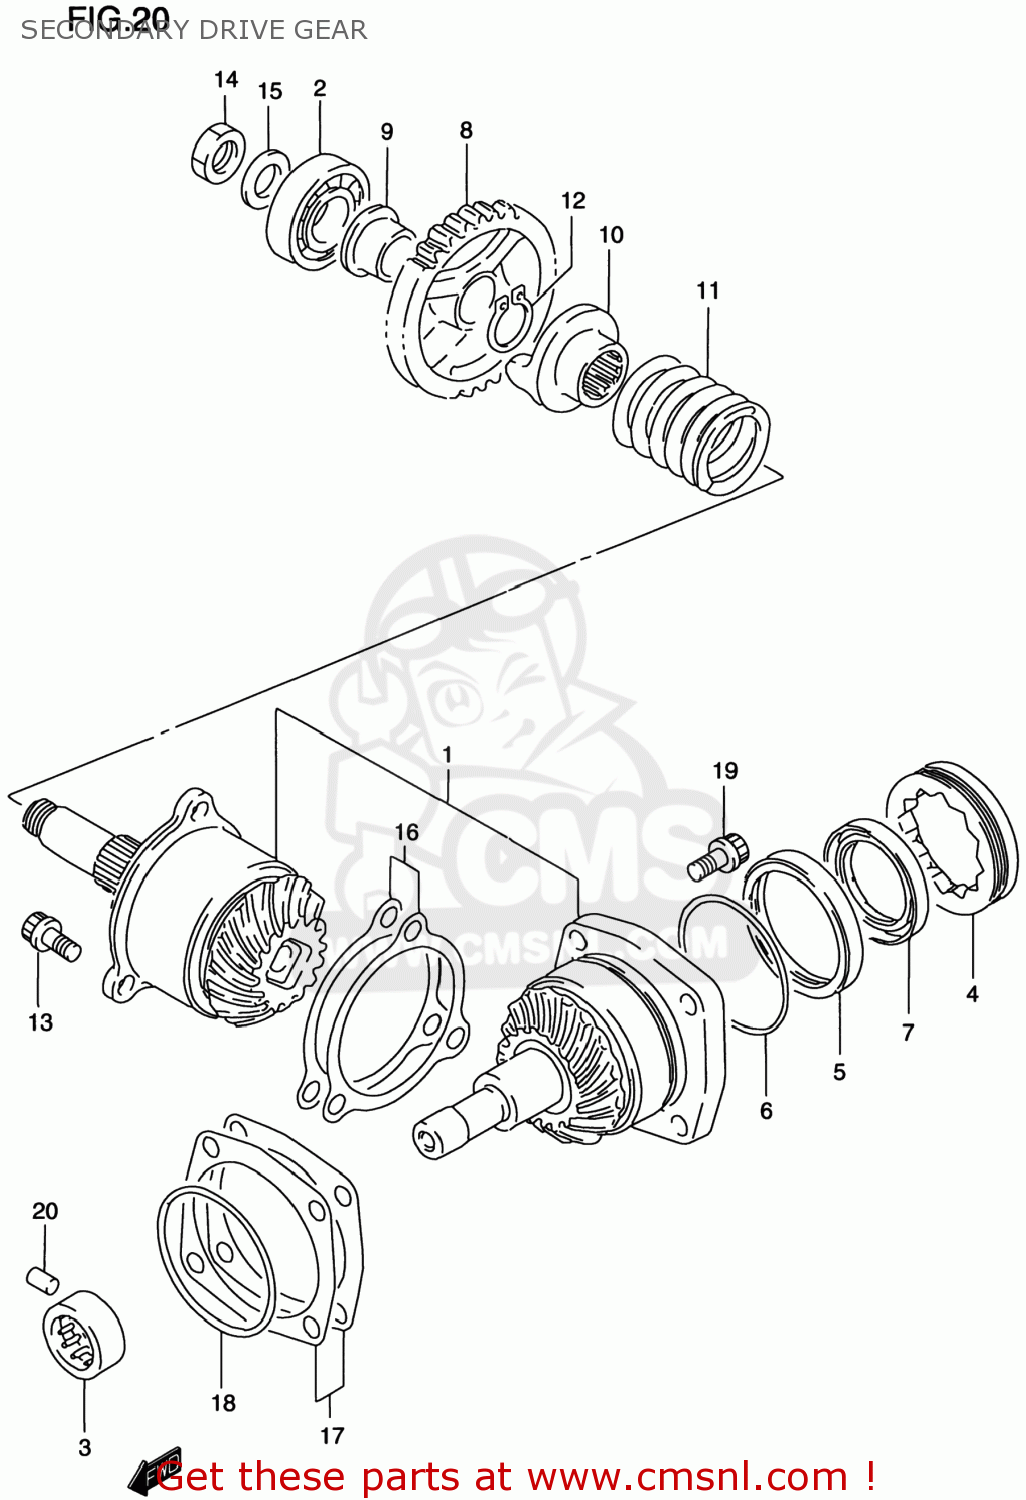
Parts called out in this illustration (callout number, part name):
1	GEAR & HOUSING SET,SECONDARY
2	BEARING(20X52X15)
3	BEARING(20X34X16)
4	STOPPER,SEC DRIVEN BEARING
5	HOUSING,OIL SEAL
6	O RING(D:1.2,ID:59.6)
7	SEAL,OIL(38X54X8.5)
8	GEAR,REDUCTION DRIVEN(NT:30)
9	BUSH,REDUCTION DRIVEN GEAR
10	DOG,OUTPUT CAM
11	SPRING
12	CIRCLIP
13	BOLT
14	NUT
15	WASHER(16X29X4)
16	SHIM SET,SEC DRIVE GEAR
17	SHIM SET,SEC DRIVEN HOUSING
18	O RING(D:2.1,ID:66.2)
19	BOLT
20	PIN
